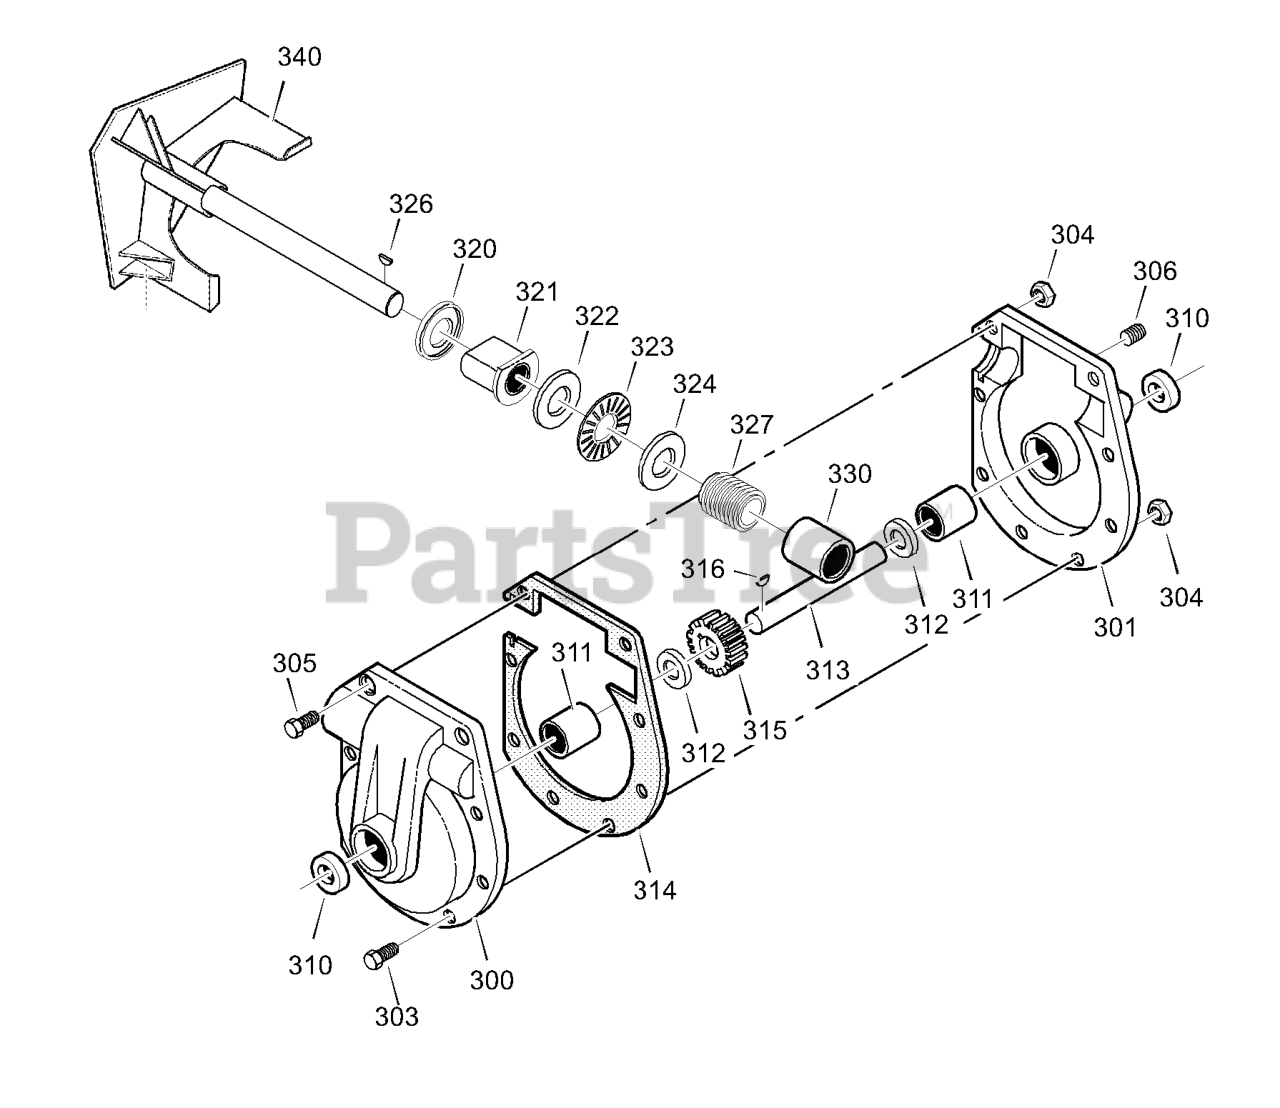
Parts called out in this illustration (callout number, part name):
300	CASE, GEAR, RH
301	CASE, GEAR, LH
303	SCREW,1/4-20X.75
304	NUT,1/4-20
305	NUT, 1/4-20 HEXKEPS
306	SCREW, 3/8-16 x 0.50
310	SEAL, OIL
311	BEARING, FL
312	WASHER, FLAT
313	SHAFT, AUGER OUTPUT
314	GASKET, GEAR BOX
315	WORM GEAR
316	KEY, WOODRUFF #61
320	BRNG, FL
321	FLANGE BEARING, IMPELLER SHAFT
322	BEARING, THRUST NEEDLE
323	PIN, SPRING
324	WASHER, THRUST
326	BRNG, FL
327	GEAR, WORM
330	BEARING
340	IMPELLER
